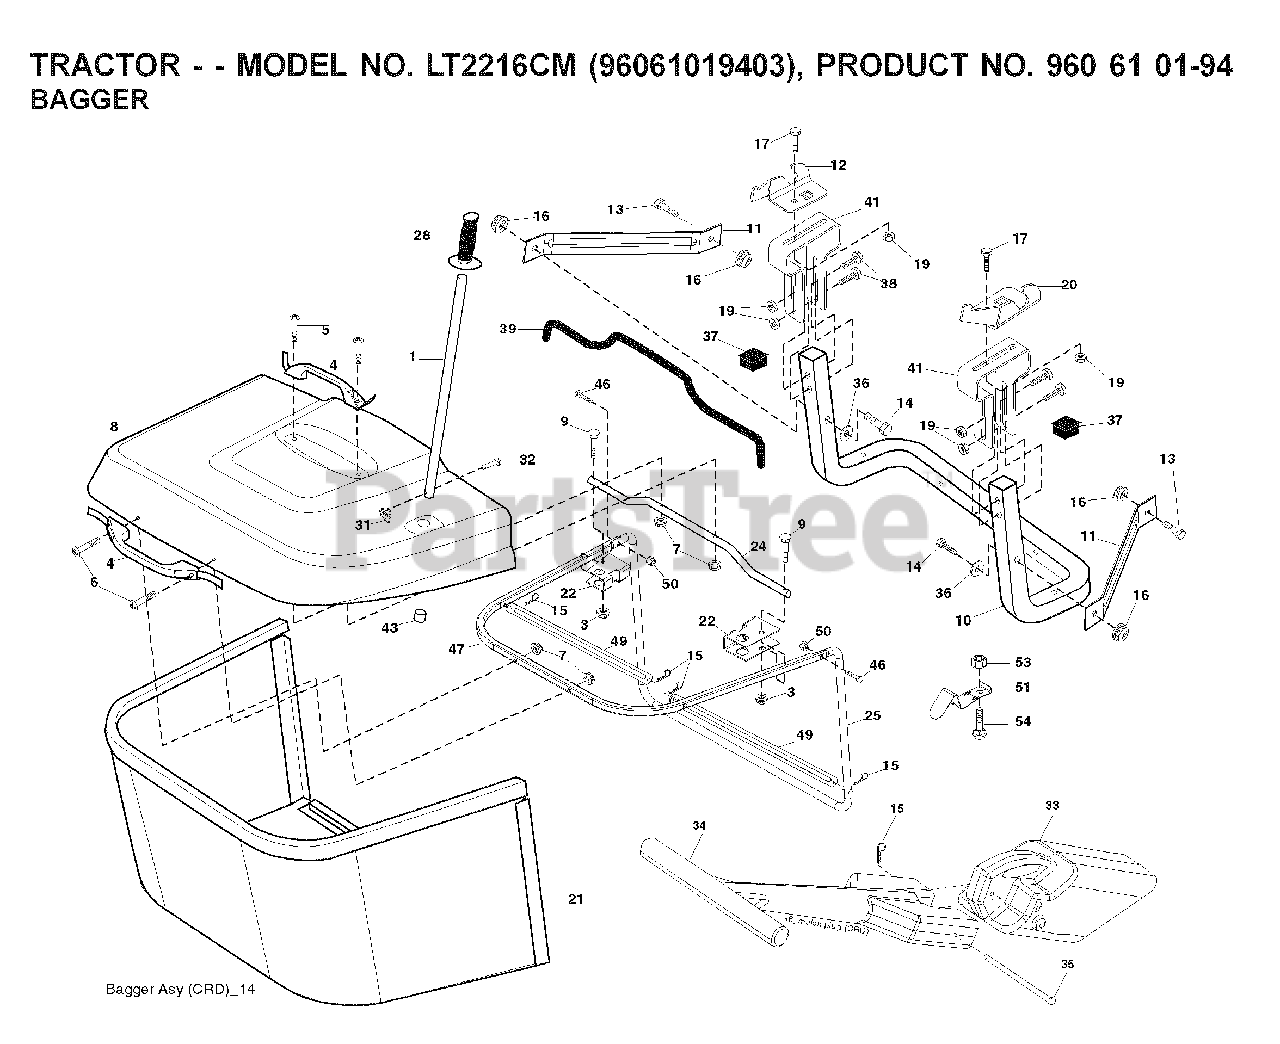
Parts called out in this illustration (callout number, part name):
1	TUBE HANDLE
3	NUT T
5	SCREW.PAN.HEAD
11	BRACKET
14	BOLT-HEX EAK
15	RETAINER-SPRNG RB
16	NUT LOCK FLG 3/8-16 UNC
17	BOLT
19	NUT LOCK HEX FLANGE 5/16-18
20	BRKT.PIVOT.RH.CRD
21	BAGGER.ASM.CRD.2007
22	BRACKET
24	TUBE
28	GRIP.HANDLE.BLACK
31	RETAINER CLIP
32	RIVET,DRILLED
33	PLUG
35	PIN
38	BOLT.5/16-18X2.5
41	BRKT, BAGGER
43	PLUG, TUBING END
46	BOLT.CARRIAGE.5/16-18
50	NUT.71038.31-18.HEX.NYLOCK
53	NUT
54	BOLT
